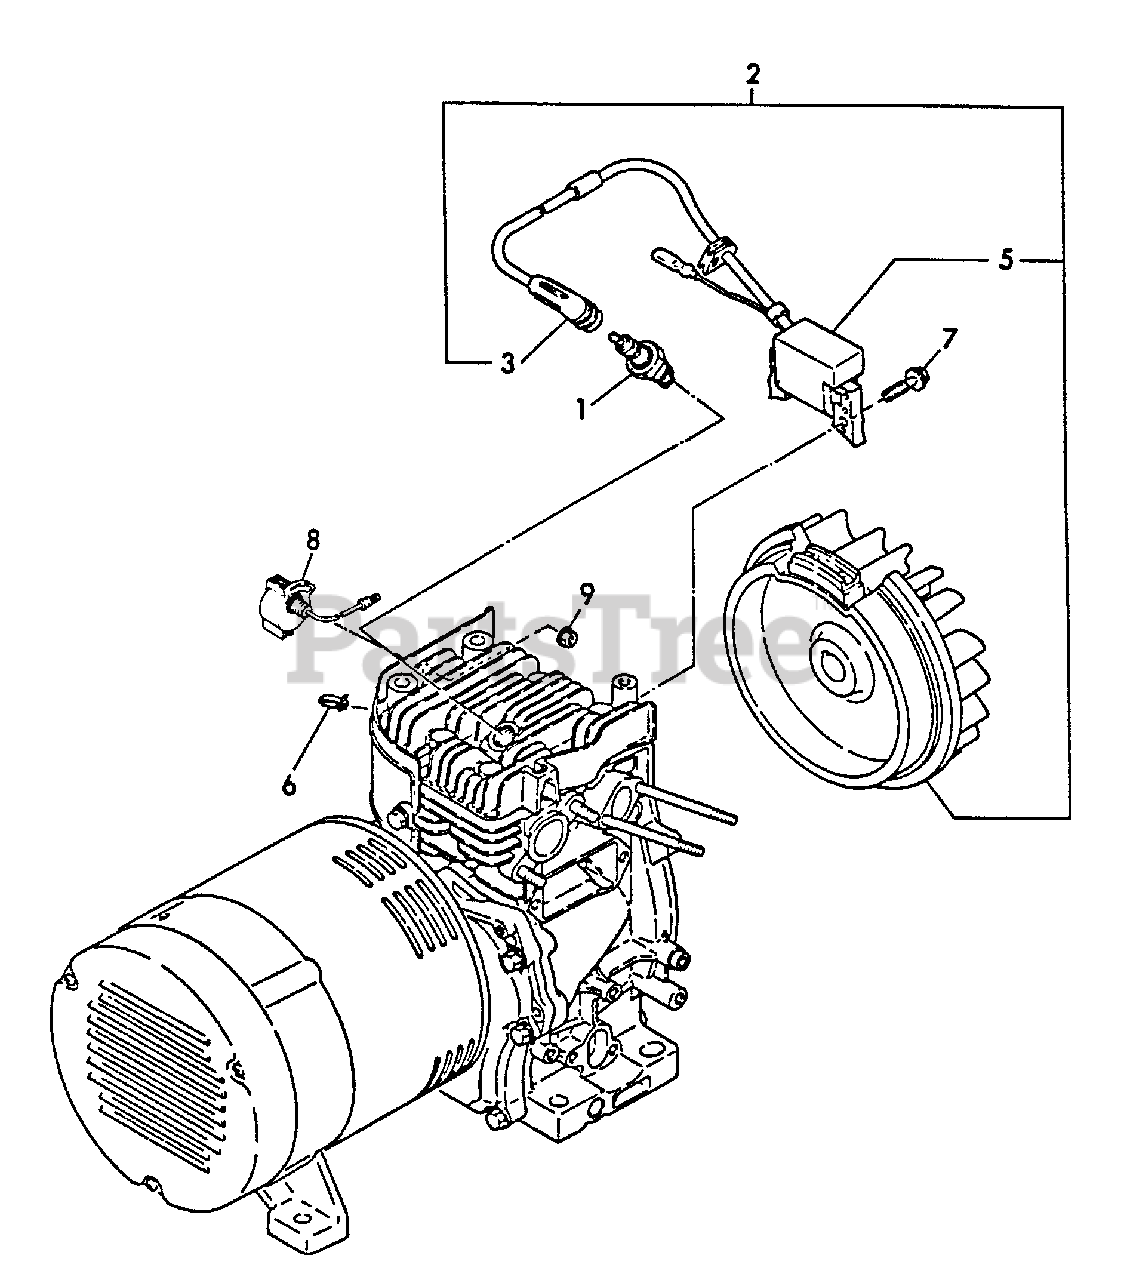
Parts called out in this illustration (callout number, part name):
1	SPARK PLUG
2	FLYWHEEL
3	CAP, PLUG
5	COIL, IGNITION
6	CLAMP
7	BOLT - 6×30
8	IGNITION SWITCH ASSY
9	U-NUT M8
